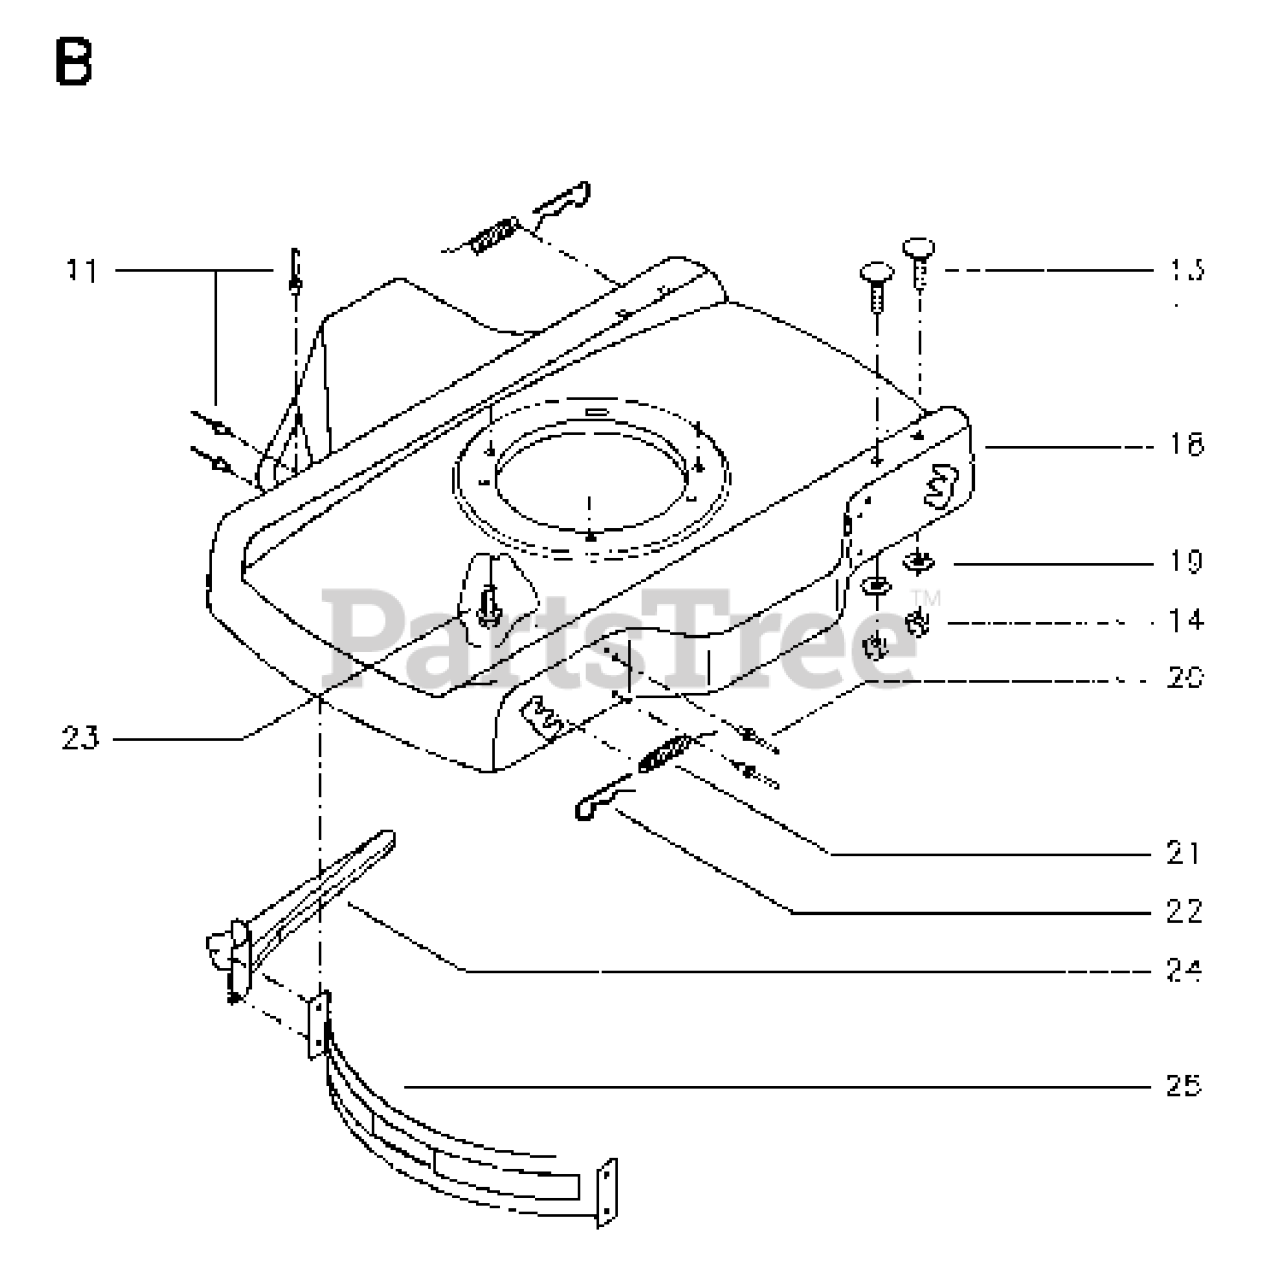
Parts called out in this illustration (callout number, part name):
11	REPL BY 516 92 38-00
14	NUT
19	SPRING WASHER
20	RIVET
